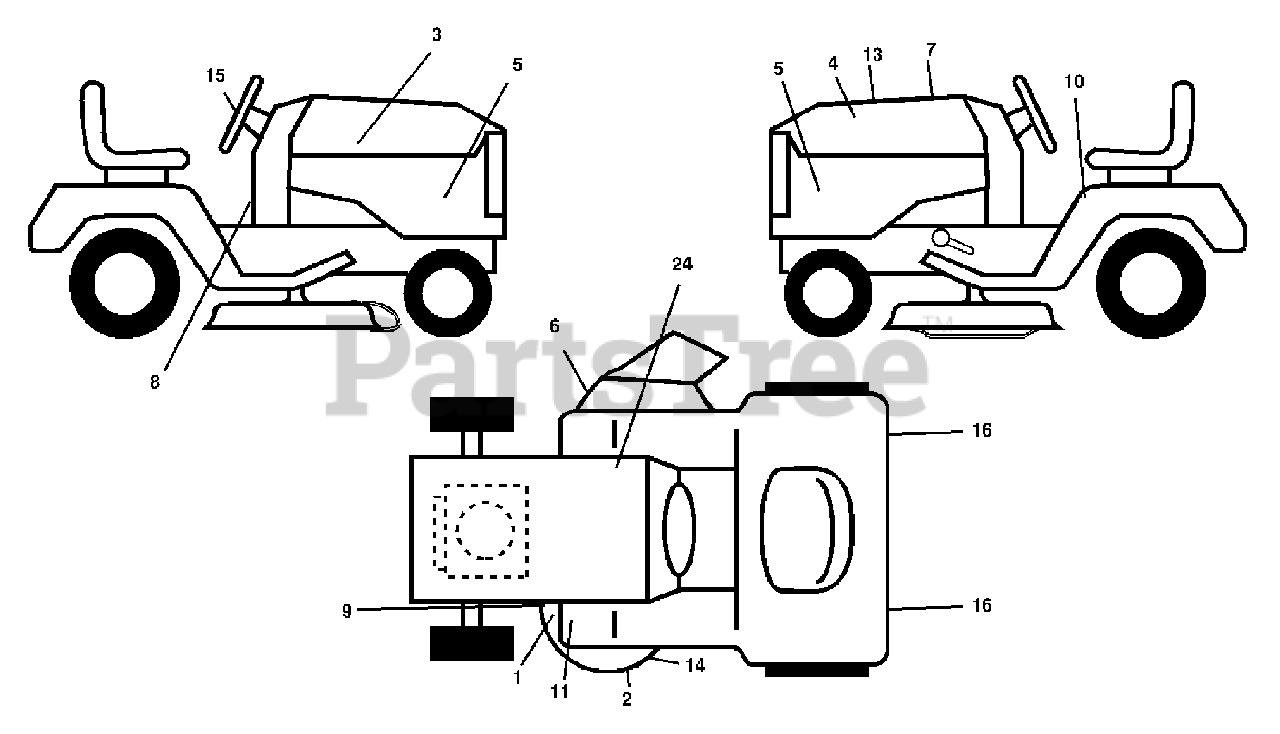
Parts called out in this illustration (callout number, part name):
1	Decal, Deck Caution
2	Decal, Deck Hvy Duty
3	Decal, Hood RH
4	Decal, Hood LH
5	Decal, Side Panel
6	Decal, Warning
7	Decal, Cust. Resp.
8	Decal, Operator
9	Decal, Mower Deck Upstop
10	Decal, Danger
11	Decal, Foot Rest
13	Decal, Replacement
14	Decal, V-Belt Schematic
15	Decal, Ins. Strg Whl
16	Reflector Tail Light
24	Decal, Btry Dngr/Psn
